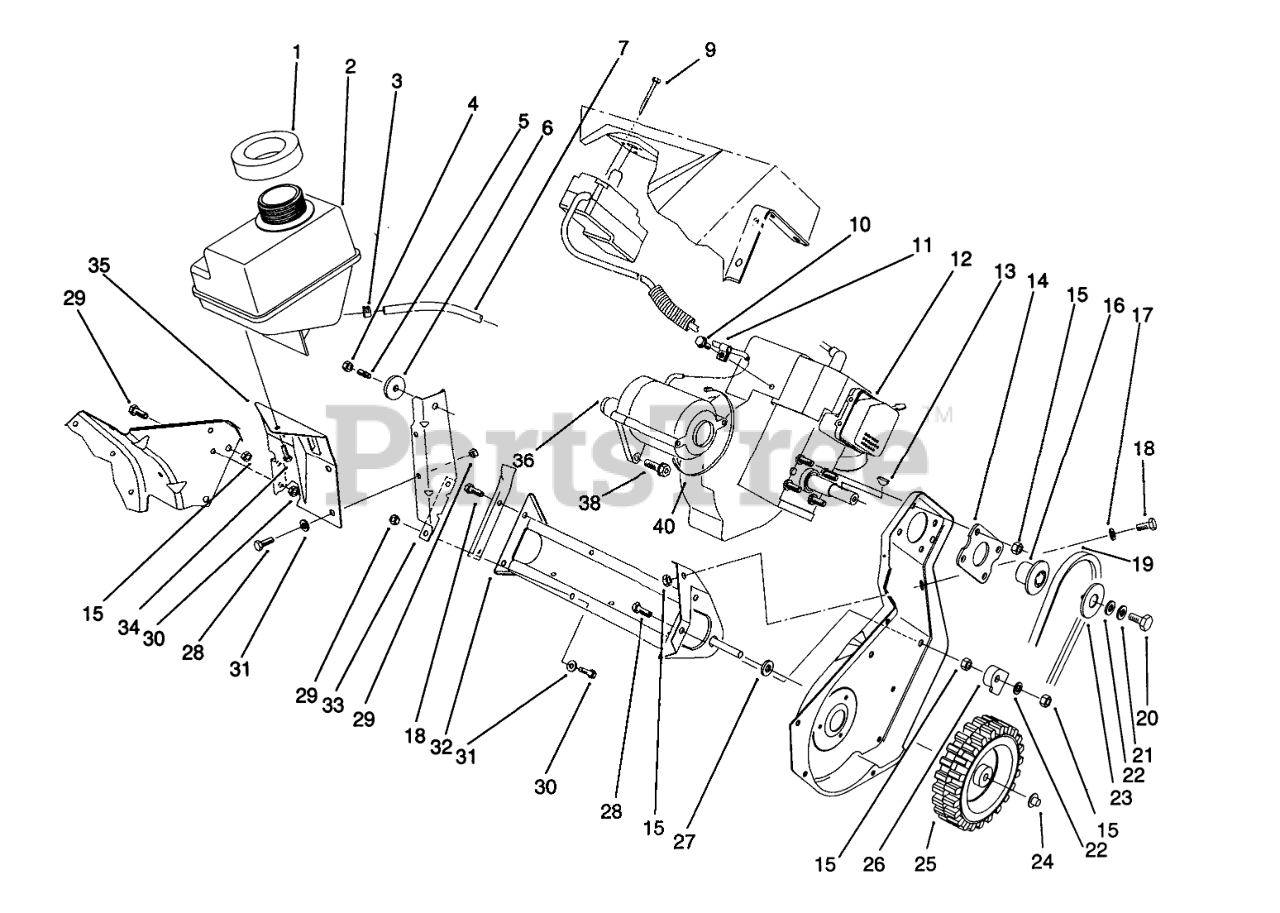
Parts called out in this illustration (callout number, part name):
1	SEAL-FOAM
2	Tank-Gas
3	Clamp
4	NUT-LOCK, NI
6	WASHER-SUPPORT, ENGINE
7	LINE-FUEL
9	SCREW-PLASTITE
10	SCREW-HWH
11	CLAMP
13	KEY-WOODRUFF
14	Plate Engine
15	NUT-LOCK, NI
16	Hub-HALF SHEAVE
17	WASHER-PLAIN
18	SCREW-HH
19	Belt-Drive
20	SCREW-HH
21	WASHER-BELLEVILLE
22	WASHER-FLAT
23	CAP-HALF SHEAVE
24	RETAINER-PUSH ON
25	WHEEL
26	GUIDE-CABLE
27	SPACER-PLASTIC
28	SCREW-HH
29	NUT-LOCK, NI
30	SCREW-HH
31	WASHER-FLAT
32	Frame Assembly
33	Support-Engine
34	SCREW-SHWH, THREAD FORMING
35	Bracket-Fuel Tank
36	Starter Motor Assembly
38	SCREW-HH, TORX
40	TIE-CABLE
